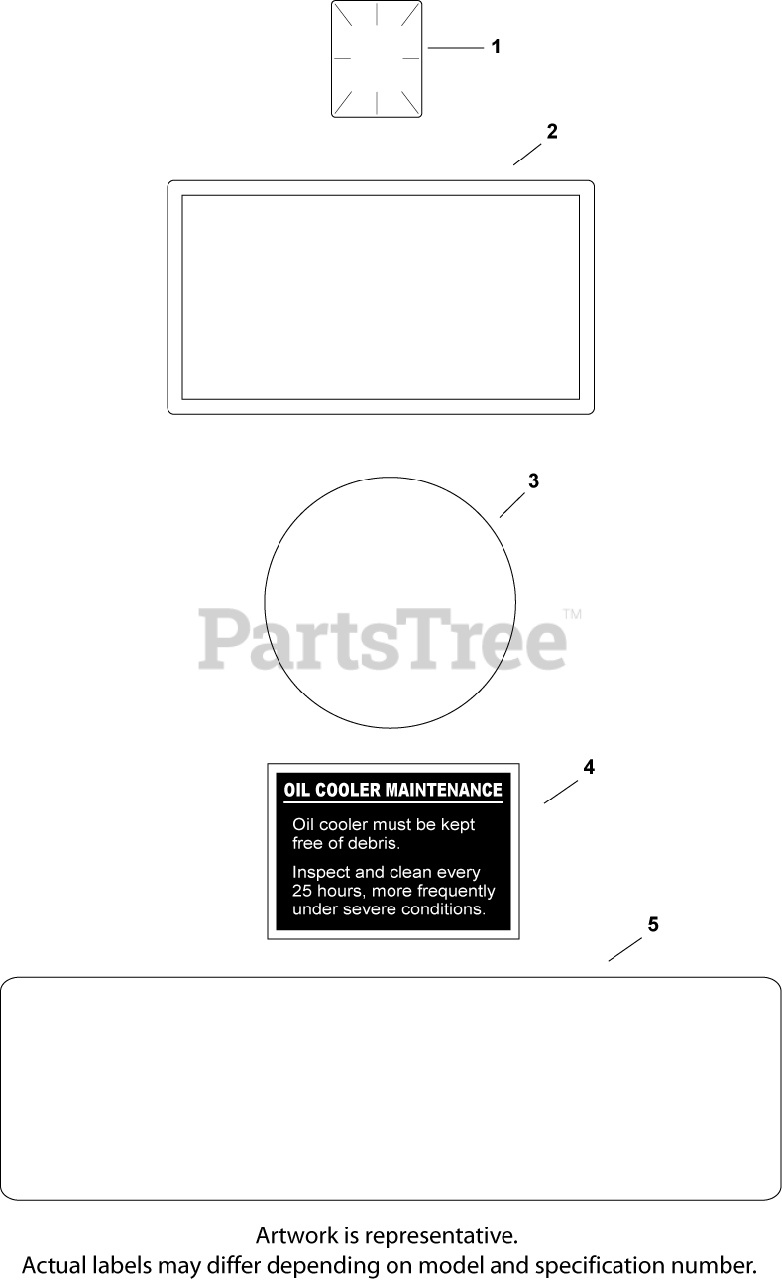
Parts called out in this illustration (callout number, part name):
1	DECAL, CLEAR LAMINATE USE 25 113 70-S
2	DECAL, AIR CLEANER
3	DECAL, GRASS SCREEN USE 24 113 499-S
4	DECAL, OIL COOLER - (#DSC)
5	DECAL, 25 HP - DISCONTINUED
